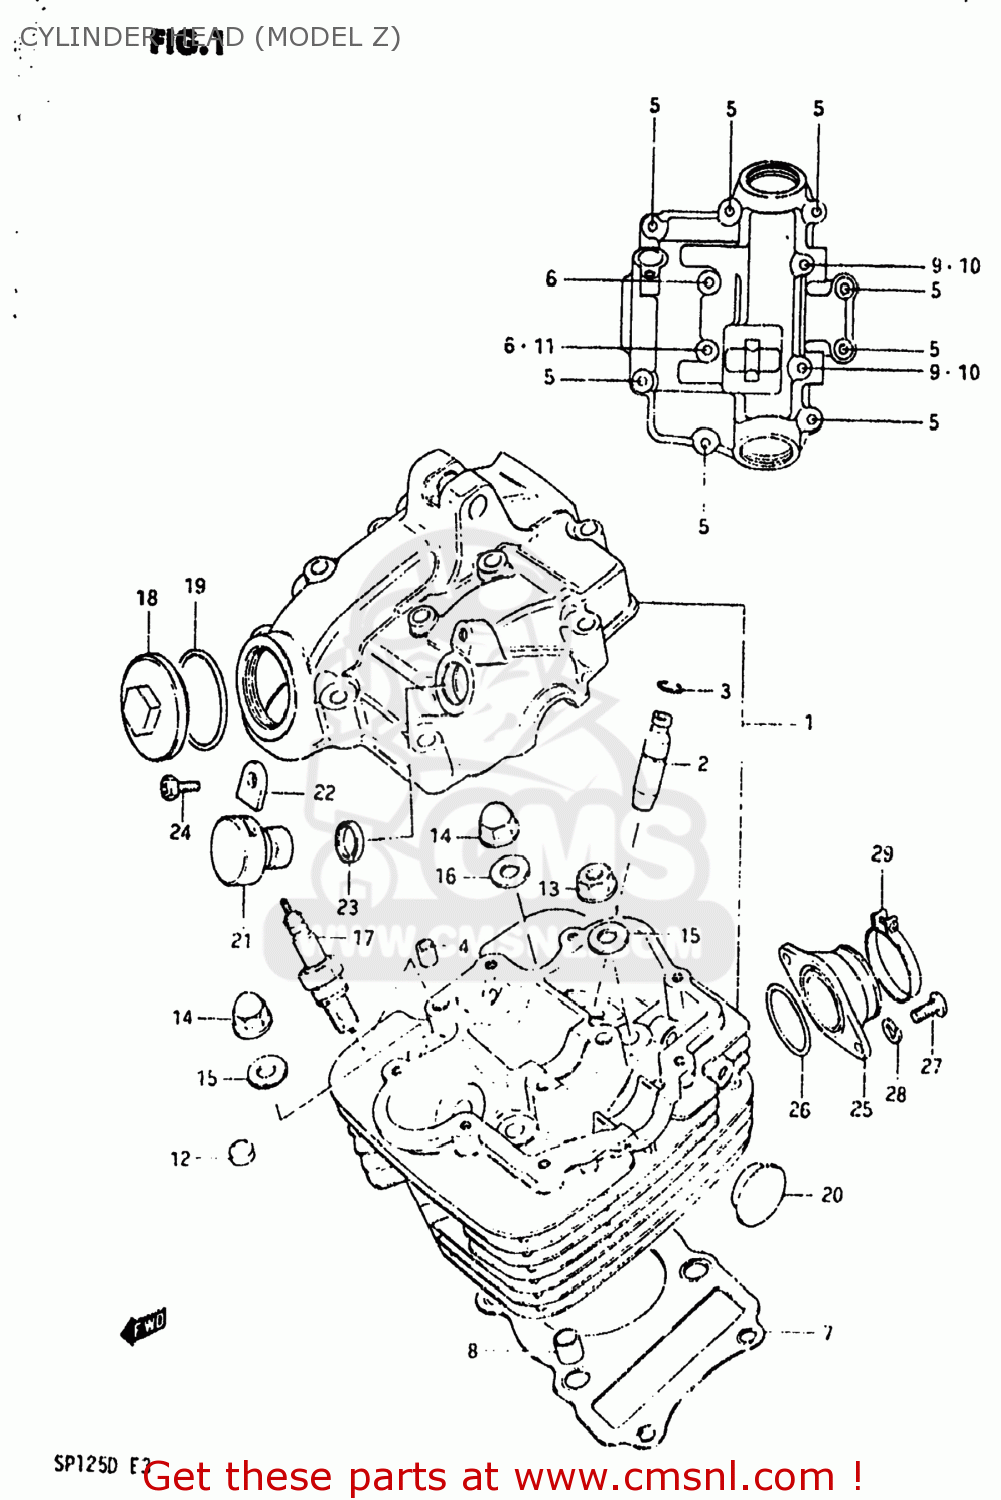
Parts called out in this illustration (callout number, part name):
1	HEAD ASSEMBLY,CYLINDER
2	GUIDE,VALVE
3	RING,SNAP
4	PIN(6.2X8X11)
5	BOLT 6X35
6	BOLT (6X60)
7	GASKET,CYLINDER HEAD
8	PIN
9	STUD 6X25
10	NUT
11	GASKET(6.2X11X1).2 (NAS)
12	PAD,CYLINDER HEAD
13	NUT
14	NUT
15	WASHER(8.5X19X2.3)
16	GASKET(8.5X20X2.3) (NAS)
17	SPARK PLUG D8EA
18	CAP,INSPECTION
19	O RING(D:3,ID:29.5)
20	PLUG(OD:22.5)
21	PLUG,TACH GEAR SLEEVE HOLE
22	PLATE,TACH DRIVE GEAR SLEEVE
23	SEAL,TACHOMETER DRIVEN
24	SCREW(5X12)
25	PIPE,INTAKE
26	O RING(D:2.4,ID:31.7)
27	SCREW
28	LOCK WASHER
29	CLAMP
